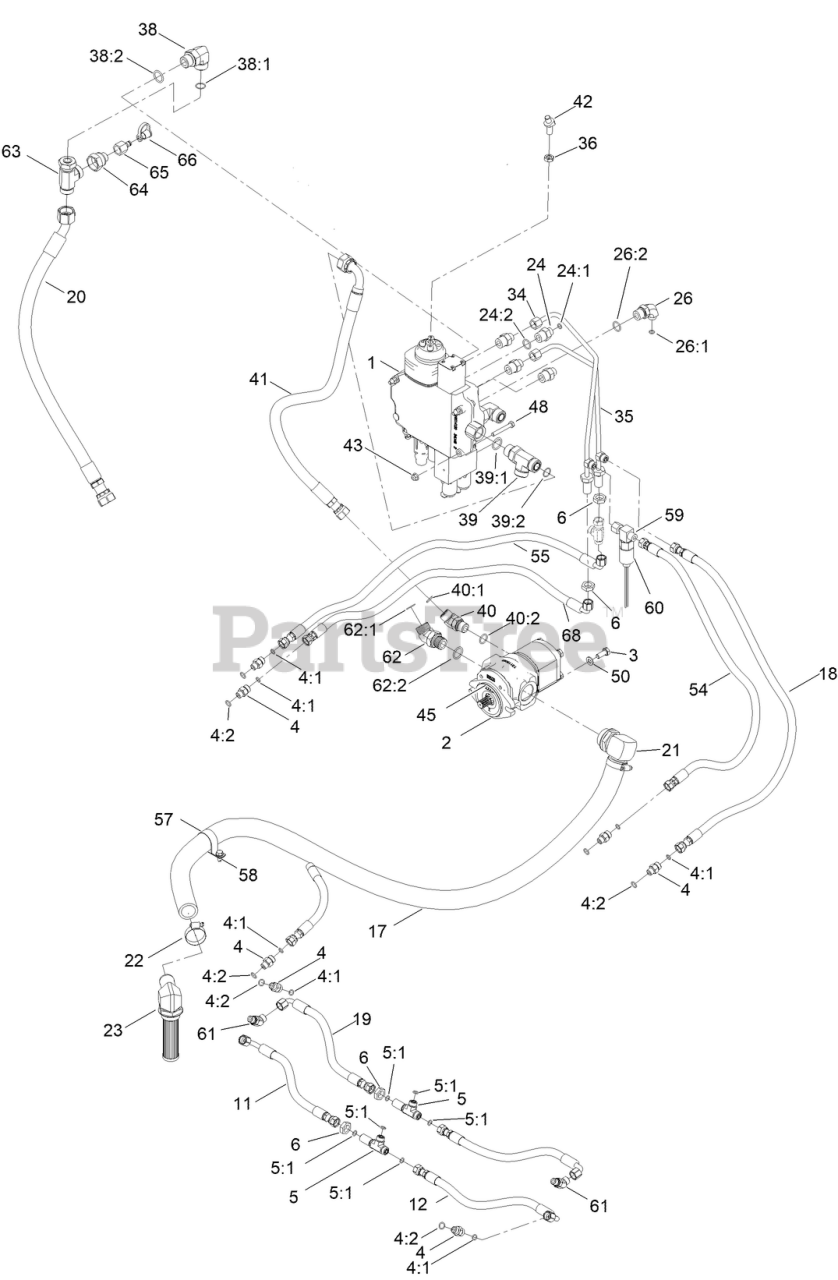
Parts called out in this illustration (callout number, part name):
1	LIFT VALVE ASM
2	GEAR PUMP ASM
3	SCREW-HH
4	FITTING-STRAIGHT
4:1	O-RING
4:2	O-RING
5	FITTING-TEE, BULKHEAD
5:1	O-RING
6	NUT-LOCK
11	HYD HOSE ASM
12	HYD HOSE ASM
18	HYD HOSE ASM
19	HYD HOSE ASM
20	HYD HOSE ASM
21	FITTING-HYD 90 SPCL
23	STRAINER FITTING ASM
24	FITTING-STR
24:1	O-RING
24:2	O-RING
26	FITTING-ELBOW 90
26:1	O-RING
26:2	O-RING
34	HYD TUBE ASM
35	HYD TUBE ASM
38	FITTING-ELBOW-90
39	FITTING-TEE
39:1	O-RING
39:2	O-RING
40	FITTING-HYD, 45 DEG
40:1	O-RING
40:2	O-RING
41	HYD HOSE ASM
42	SHAFT-CONTROL
43	NUT-HF, NI
45	O-RING
48	SCREW-HH
50	WASHER-FLAT
54	HYD HOSE ASM
55	HYD HOSE ASM
57	CLAMP-R
58	SCREW-HWH
59	FITTING-HYD, SPECIAL
60	SWITCH-PRESSURE
61	FITTING-ELBOW, 45 DEG
62	FITTING-45 DEG
62:1	O-RING
62:2	O-RING
63	FITTING-HYD
64	FITTING-STRAIGHT
65	FITTING
66	CAP-DUST
68	HYD HOSE ASM
